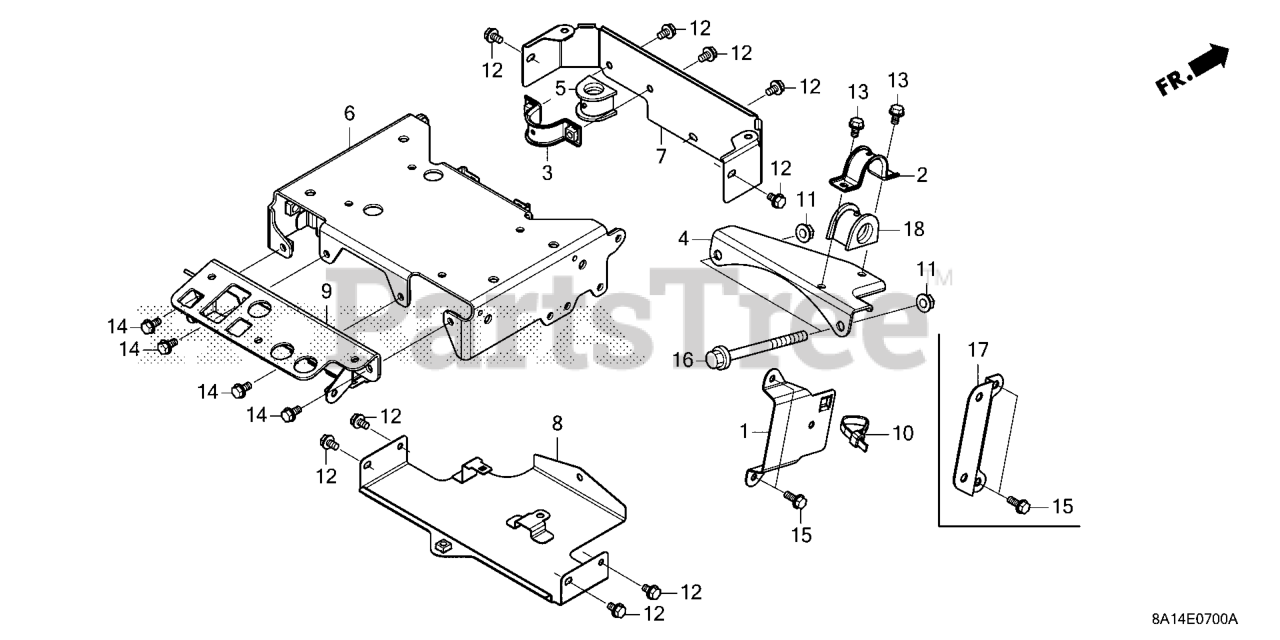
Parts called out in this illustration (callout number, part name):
5	GROMMET, HARNESS
7	FRAME, FR.
8	FRAME (LOWER)
9	BASE, CONTROL
12	BOLT, FLANGE (6X10)
14	BOLT, FLANGE (6X12) Use from Engine SN 2086984.
15	BOLT, FLANGE (6X14)
17	STAY, MOTOR HARNESS
